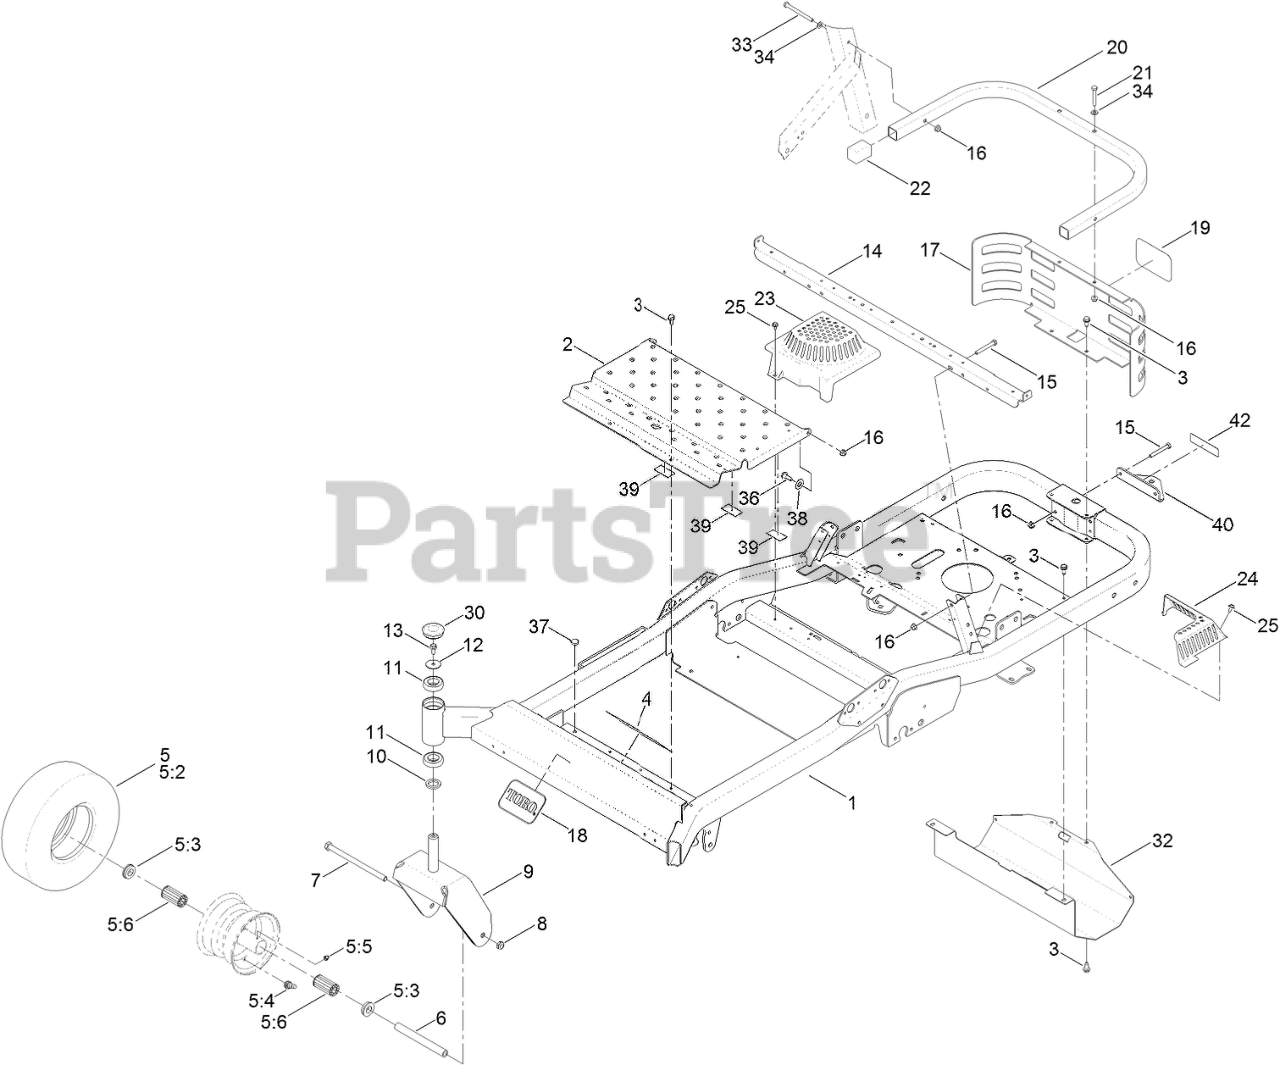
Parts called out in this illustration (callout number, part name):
1	FRAME ASM
2	PAN-FLOOR
3	SCREW-HWHTF
4	DECAL-DANGER
5	TIRE AND WHEEL ASM
5:3	BUSHING-FLANGE
5:4	VALVE
5:5	FITTING-ZERK
5:6	BEARING
6	SPANNER-WHEEL, CASTER
7	SCREW-HH
8	NUT-LOCK, NI
9	CASTER FORK ASM
10	WASHER-THRUST
11	BEARING-BALL
12	WASHER-FLAT
13	SCREW-HHF
14	SUPPORT-SEAT
15	SCREW-HH
16	NUT-HF, NI
17	GUARD-REAR
18	DECAL
20	TUBE-GUARD
21	SCREW-HH
23	COVER-FAN, RH
24	COVER-FAN, LH
25	SCREW-HHFTF
30	CAP-GREASE
32	SHIELD-HEAT
33	SCREW-HH
34	WASHER-PLAIN
36	SCREW-SHOULDER
37	BUMPER
38	WASHER-TEFLON
39	PAD-RUBBER
40	BRACKET-HITCH
